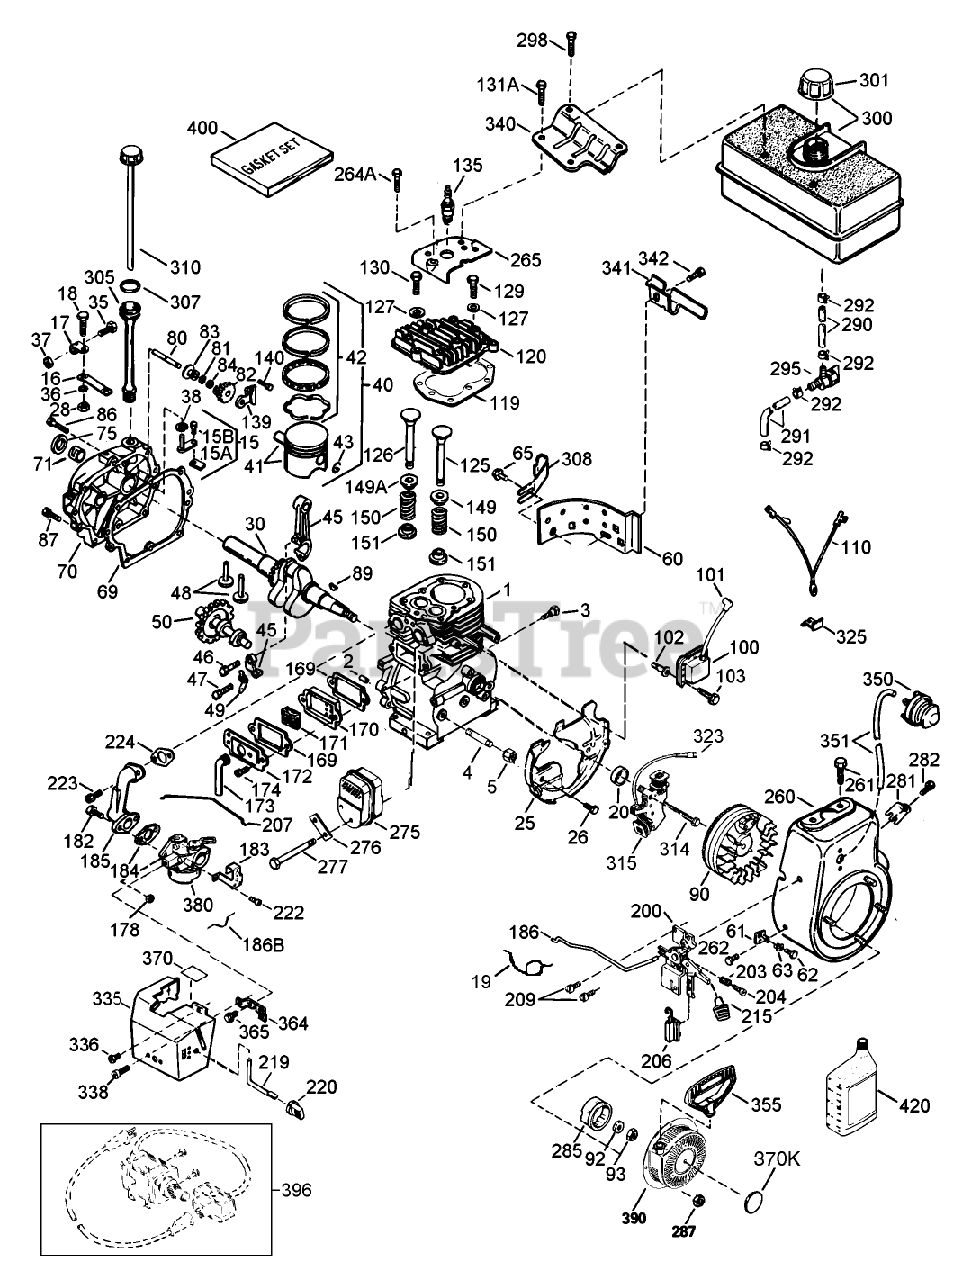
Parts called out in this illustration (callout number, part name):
1	Cylinder Asm (Includes 2, 20, 72)
2	Pin-Dowel
3	Screw (1/4-20x1/2)
4	Nipple-Pipe
5	Cap-Pipe
15	Rod, Governor (Incl. Nos.62 63)
15A	Yoke-Governor
15B	Screw (6-40x5/16)
16	Lever-Governor
17	Clamp-Lever, Governor
18	Screw
19	Spring-Throttle
20	Seal-Oil
25	Baffle-Housing, Blower
26	Screw (1/4-20x19/32)
28	Nut-Lock
30	Crankshaft
35	Screw
36	Washer-Lock
37	Nut-Lock
38	Ring-Retaining
40	Piston, Pin Ring Assy.(Std.) (Incl. Ref. #24A, 25 26)
40	Piston, Pin Ring Assy. (.010 oversize) (Incl. Ref. #24A, 25 26)
40	Piston, Pin Ring Assy. (.020 oversize) (Incl. Ref. #24A, 25 26)
41	Piston Pin Assy. (Std.) (Incl. Ref. #26)
41	Piston Pin Assy. (.010 oversize) (Incl. Ref. #26)
41	Piston Pin Assy. (.020 oversize) (Incl. Ref. #26)
42	Ring Set (Std.)
42	Ring Set (.010" OS)
42	Ring Set (.020" OS)
45	Rod Assy., Connecting (Incl. Ref. #28 28A)
46	Bolt-Rod
47	Bolt-Rod
48	Lifter-Valve
49	Dipper-Oil
50	Camshaft (MCR)
60	Extension-Housing, Blower
61	Bracket
62	Screw (8-32 x 3/8)
63	Grommet
65	Screw
69	Gasket-Cover, Cylinder
70	Cover-Cylinder (Includes 71, 75, 80)
71	2025A77 WIZARD ROTA
75	Seal-Oil
80	Shaft-Governor
81	Washer-Flat
82	Gear Assy., Governor (Incl. Ref. #45)
83	Spool-Governor
84	Ring-Retaining
86	Screw (1/4-20x1-3/16)
87	Screw (1/4-20x1-11/16)
89	Key-Flywheel
90	Flywheel ASM
92	Washer-Belleville
93	Nut-Flywheel
100	Solid State ASM
101	Cover-Spark Plug
103	Screw (T-15, 10-24 x 15/16)
110	Ground Wire
119	Gasket-Head, Cylinder
120	Head-Cylinder
125	Valve, Exhaust (Standard)(Incl. No. 9)
125	Valve, Exhaust (1/32" oversize)(Incl. No. 9)
126	Valve, Intake (Std.) (Incl. Ref. #58)
126	Valve, Intake (1/32" oversize) (Incl. Ref. #58)
127	Washer-Flat
129	Screw (5/16-18x1-25/32)
130B	Screw (5/16-18x1-1/2)
131A	Screw
135	Spark Plug-Resistor (R J19 L M)
139	Bracket-Gear, Governor
140	Screw (10-24x1/2)
149	Cap-Spring, Valve
149A	51106 GILSON ROTARY
150	Spring-Valve
151	Keeper-Spring, Valve
169	Gasket-Cover, Valve
170	Body-Breather
171	Element-Breather
172	Cover-Valve
173	Tube-Breather
174	Screw
178	Nut and Lock Washer (1/4-28)
182	Screw (1/4-28x1)
183A	Bracket-Choke
184	Gasket-Carburetor To Intake Pipe
185	Pipe-Intake
186	Link-Governor
186A	Spring-Choke
200	Bracket-Control (Includes 19, 203, 204, 206)
203	Spring-Compression
204	Screw
206	Terminal
207	Link-Throttle
209	Screw (10-32 x 1/2)
215	Knob-Control
219	Rod-Choke
220	Knob-Control
222	Screw (10-32 x 1/2)
223	Screw (T-30, 5/16-18x1-3/32)
224	Gasket-Pipe, Intake
260	Housing-Blower
261	Screw (5/16-18x3/4)
262	Screw
264A	Screw (1/2-20x5/8)
265	Cover-Cylinder Head
275	Muffler
276	62513 SNWTHWR W/284
277	Screw (5/16-18x4-3/16)
281	Screw
282	Screw (8-32 x 3/8)
285	Cup-Starter
287	Nut and Lock Washer (1/4-28)
290	Line-Fuel (8.62)
291	Line-Fuel
292	Clamp-Line, Fuel
295	Valve-Shut Off, Fuel
298	Screw (1/4-15x7/8)
300	Tank-Fuel (Includes 292, 301)
301	Cap-Fuel
305	Tube-Fill, Oil
307	O-Ring
308	Clip-Tube, Fill
310	Gauge Oil ASM
314	Screw (1/4-20 x 3/4)
315	Coil-Alternator, 18 Watt (Includes 323)
323	Terminal
325	Clip-Wire
335	Cover-Carburetor
336	Screw (10-32x1/2)
338	Screw (10-32 x 3/8)
340	Bracket-Tank, Fuel
341	Bracket-Tank, Fuel (Black)
342	Screw (1/4-20x19/32)
350	Primer-Asm
351	Line-Primer
355	Handle-Starter, Mitten Grip
364	Bracket-Carburetor
365	Screw (8-32x27/64)
370	Decal-Lubrication
370K	Decal-Tecumseh Logo for Top of Recoil Starter
380	Carburetor (Incl. Ref. #184)
390	Starter-Rewind
396	Starter-Electric (110 Volt)
400	Gasket Set
420	Oil-Engine (SAE 5W30)
